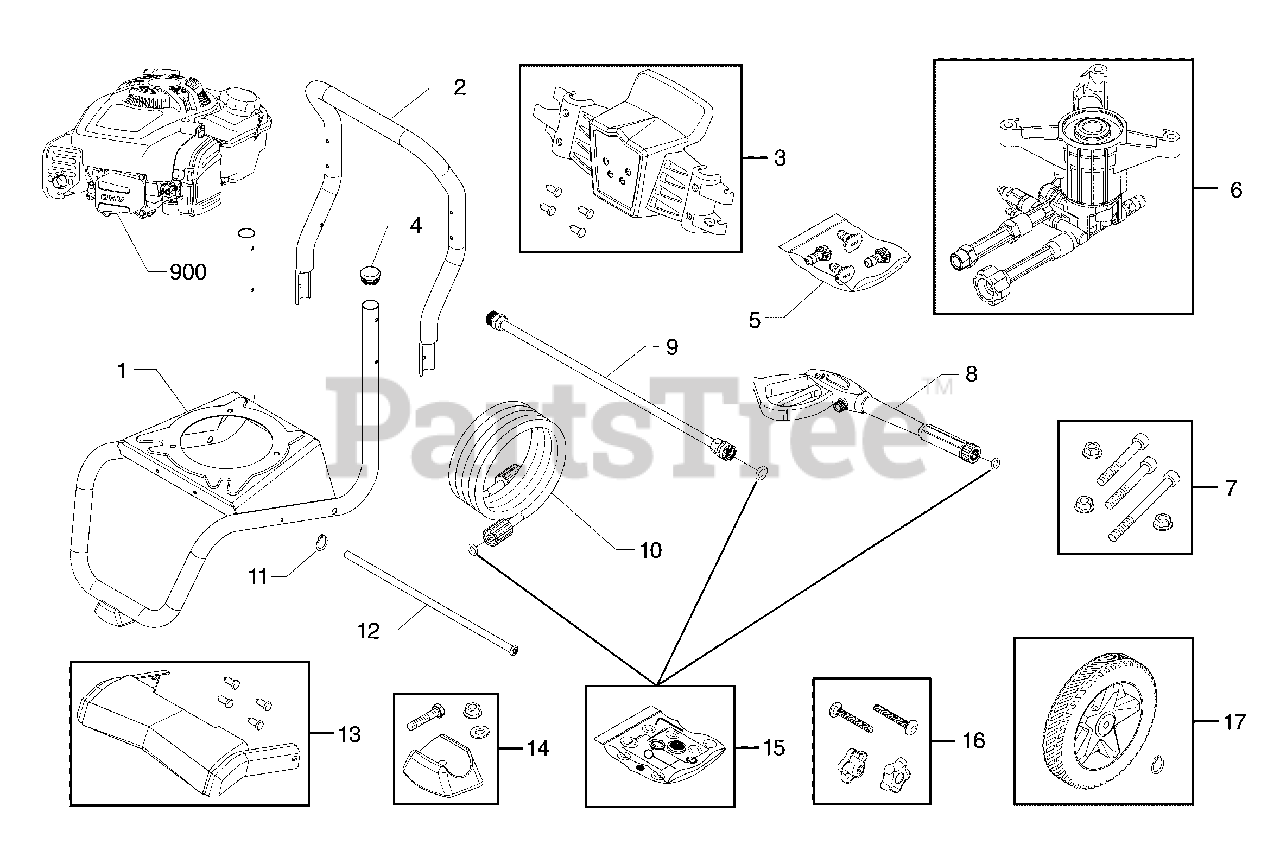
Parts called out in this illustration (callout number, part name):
5	KIT, QC Nozzles
7	KIT, Hardware, Pump Mounting
8	GUN
9	EXTENSION, QC
14	MOUNT, Vibration
16	KIT, Hardware, Handle
